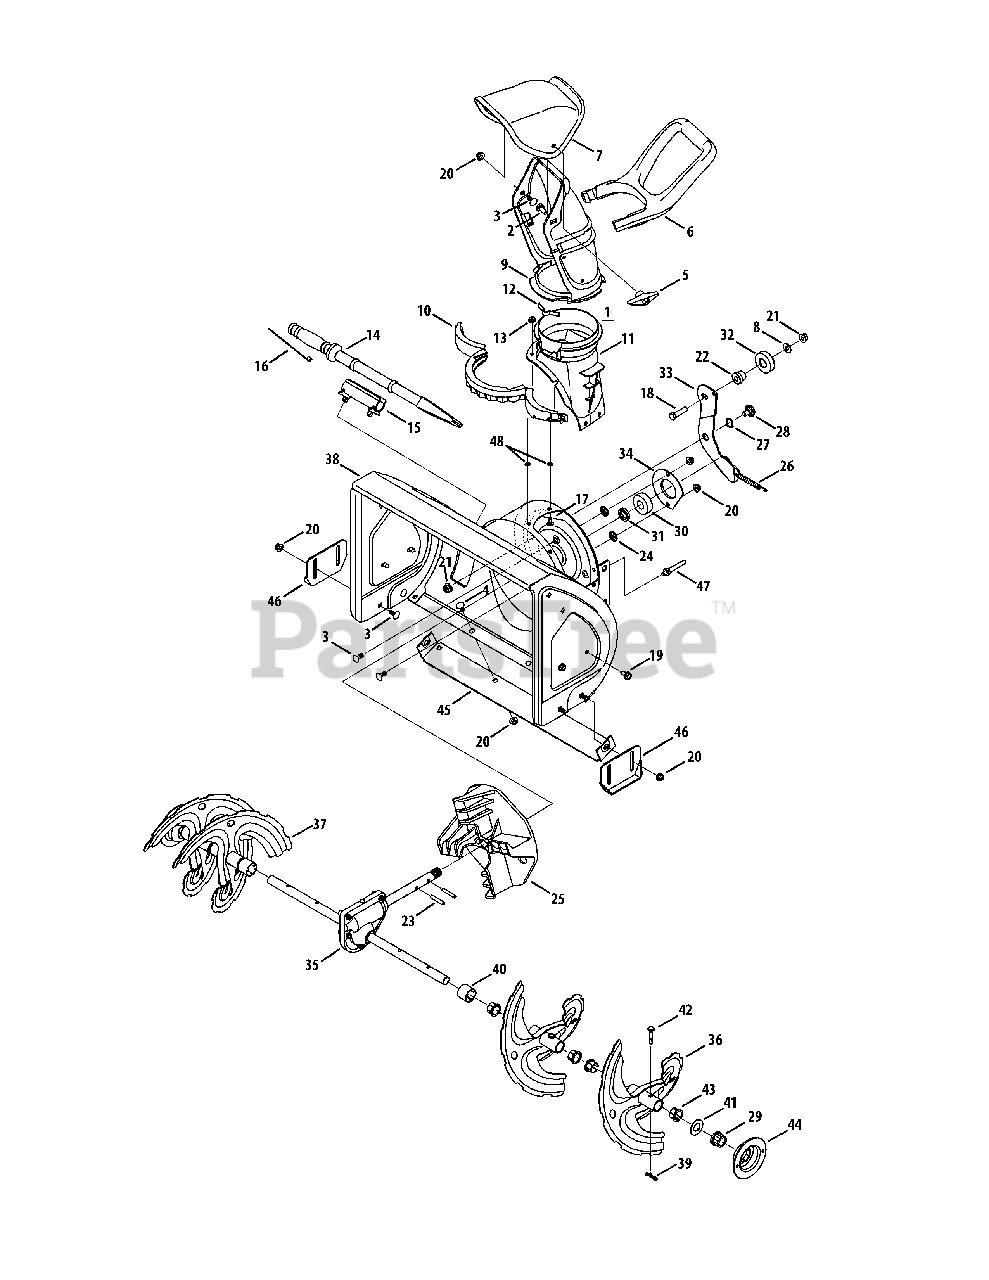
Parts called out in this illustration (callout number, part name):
1	Chute Assembly
2	Carriage Bolt 5/16-18 x 1.0"
3	Carriage Bolt 5/16-18
4	Carriage Bolt 5/16-18 x .62
5	Wing Knob 5/16-18
6	Chute Handle
7	Upper Chute
8	Flat Washer .385 x .87 x .06
9	Lower Chute
10	Chute Ring
11	Chute Adapter 5" Dia.
12	Chute Adjustment Spring
13	Flange Lock Nut 1/4-20
14	Clean-out Tool
15	Clean-out Tool Mount
16	Cable Tie
17	Carriage Screw 1/4-20 x 0.62"
18	Hex Bolt 3/8-16 x 1.50"
19	AB Screw 5/16-18 x .750
20	Flange Lock Nut, 5/16-18
21	Flange Lock Nut, 3/8-16
22	Shoulder Spacer
23	Spiral Pin
24	Push On Nut
25	Impeller
26	Extension Spring
27	Wave Washer
28	Shoulder Screw 3/8-16
29	Hex Flange Bearing
30	Ball Bearing
31	Spacer
32	Flat Idler
33	Auger Idler Bracket
34	Bearing Housing
35	Auger Gearbox Assembly
36	Auger Assembly - LH
37	Auger Assembly - RH
38	Auger Housing, 22"
39	Bow Tie Cotter Pin 72
40	Spacer, 1.25 x.75 x 1.00
41	Flat Washer
42	Shear Pin,.25 x 1.50
43	Flange Bushing
45	Shave Plate 2.25 x 21.66 LG
47	Belt Keeper
48	Push Nut
